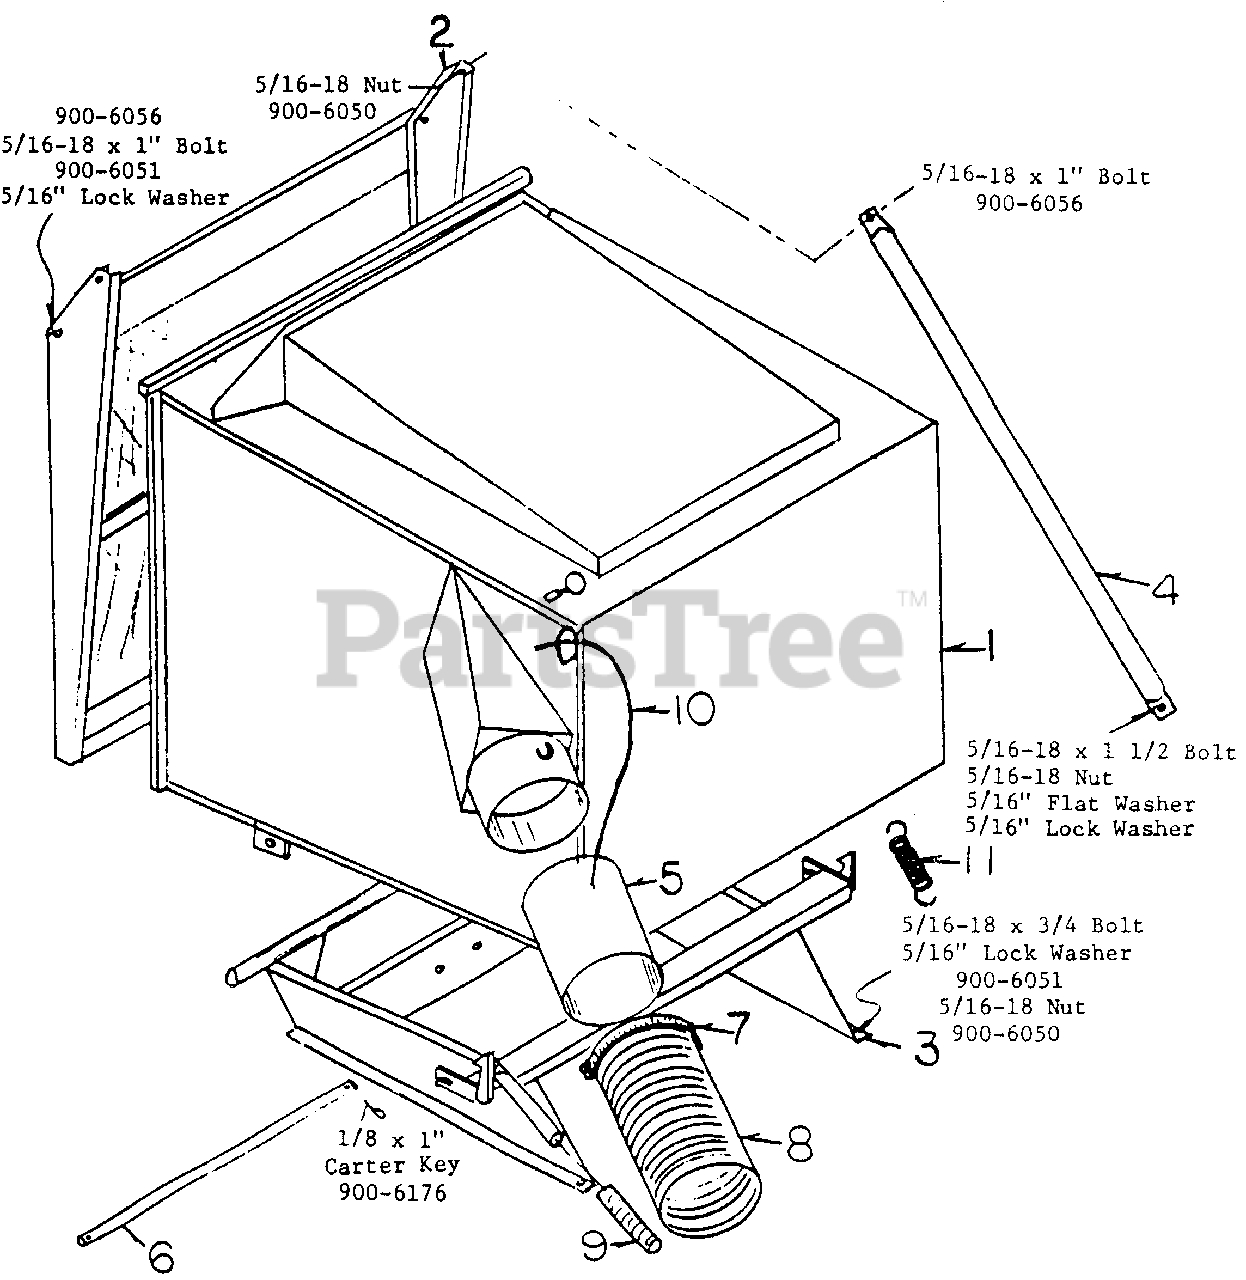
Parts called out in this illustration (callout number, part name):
1	GRASS BOX
3	BOX MOUNT
4	DOOR LINKCAGE
5	MALE TUBE
8	HOSE
9	HANDLE GRIP
10	MALE TUBE ROPE
